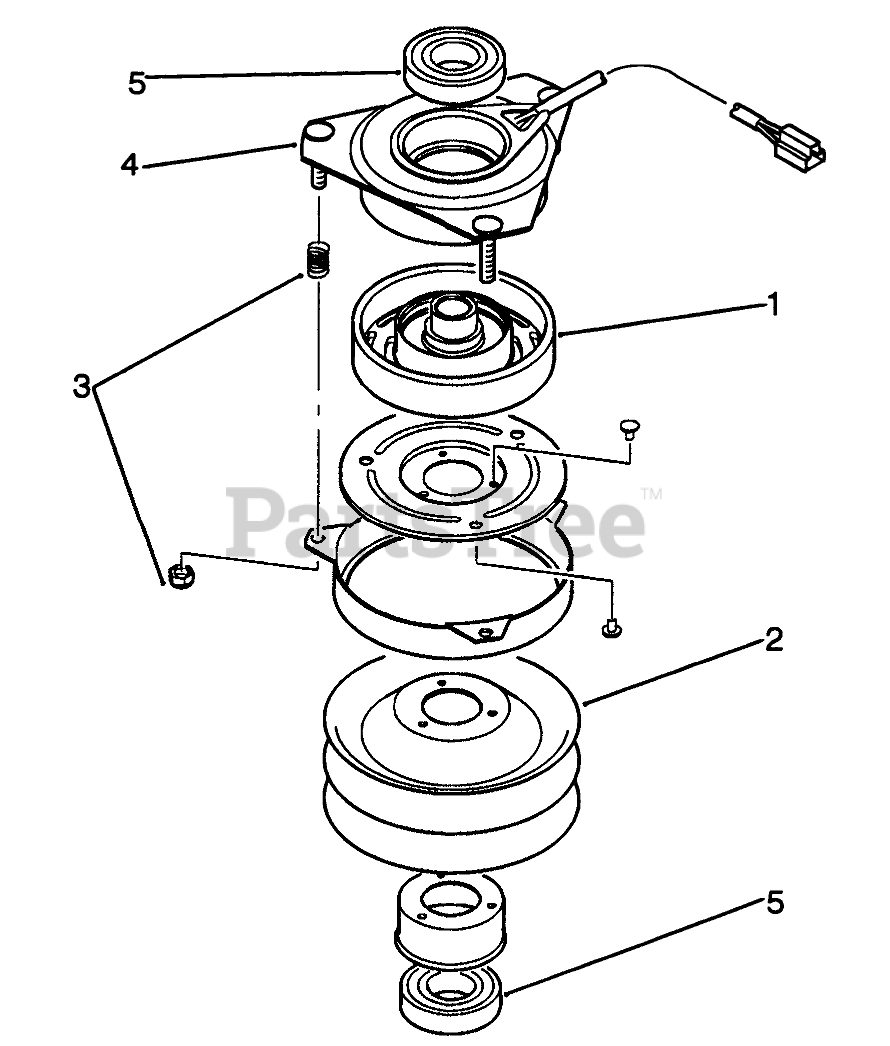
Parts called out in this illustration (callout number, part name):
1	ASS'Y-ROTOR
2	ASS'Y-ARMATURE
3	ACC-NUTS & SPRINGS
4	ASS'Y-FIELD
5	BEARING-ELEC CLUTCH
